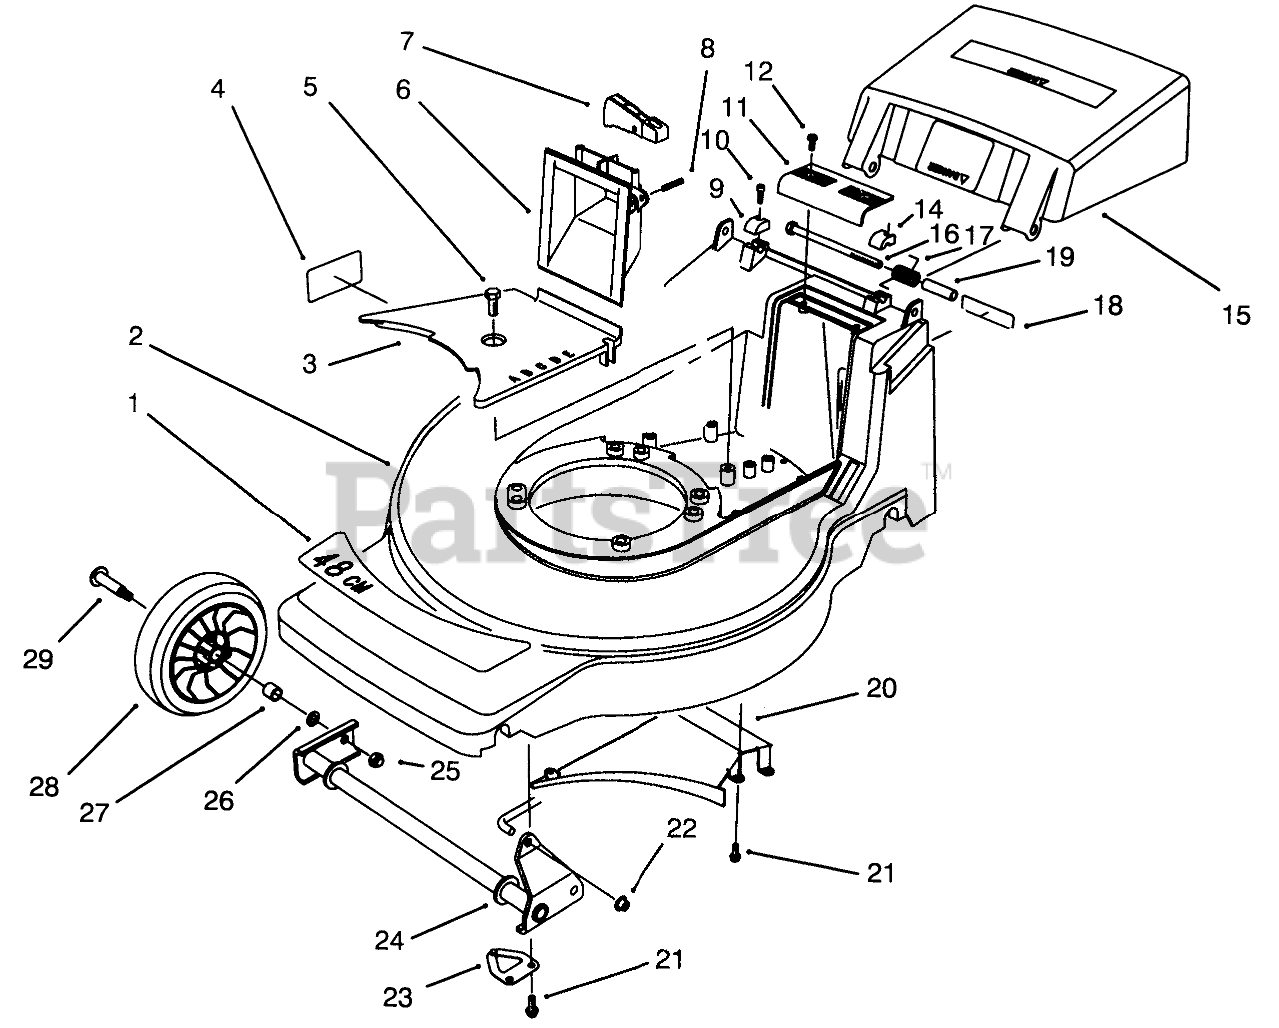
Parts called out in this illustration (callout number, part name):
1	DECAL - DECK 48 CM
2	Housing-48cm (Incl. Ref. #4)
3	BELT COVER
4	DECAL - DIN/DANGER
5	SCREW-HWHTF
6	GRIP - LOWER
7	TRIGGER - HOC
8	PIN-SPIRAL
9	CAP-HINGE BOLT, RH
10	SCREW-HSH
11	GRIP-UPPER
12	SCREW-PPH, PLASTITE
14	CAP-HINGE BOLT, LH
15	Door Discharge
16	SCREW-HH
17	SPRING-DOOR
18	DECAL FRENCH REGUL.
19	SPACER-DOOR
20	Ramp-Discharge
21	SCREW-HWH
22	NUT-PUSH
23	SHAFT RETAINER ASM
24	FRONT PIVOT WA
25	NUT-HEX
26	WASHER
27	BUSHING
28	Wheel & Tire Assembly (Incl. Ref. #27)
29	BOLT-WHEEL
